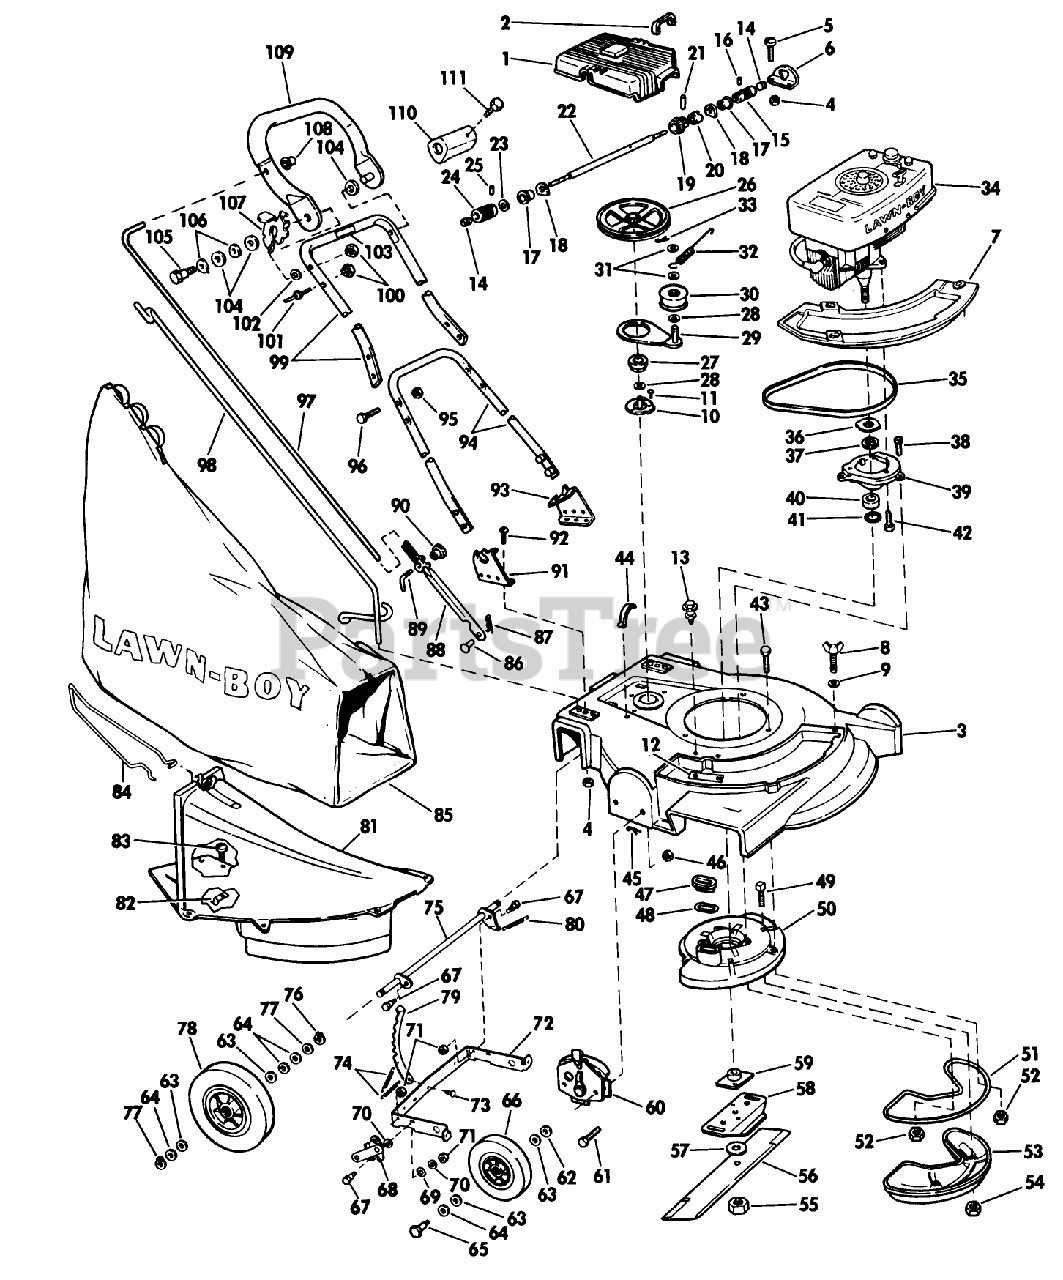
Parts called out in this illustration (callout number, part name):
8	WING SCREW LAWRE
14	GREASE PLUG
26	PULLEY&OILER FELT (13)
48	GASKET S
54	LOCKNUT E
55	NUT-BLADE
59	PLATE AND COLLAR ASM
62	WASHER WROUGHT
65	BOLT WHEEL
66	WHEEL & TIRE KIT
67	BOLT RB&W
70	WASHER S
71	STOP NUT
77	RET RING
92	SCREW S
104	WASHER M
105	BOLT PIONEER
